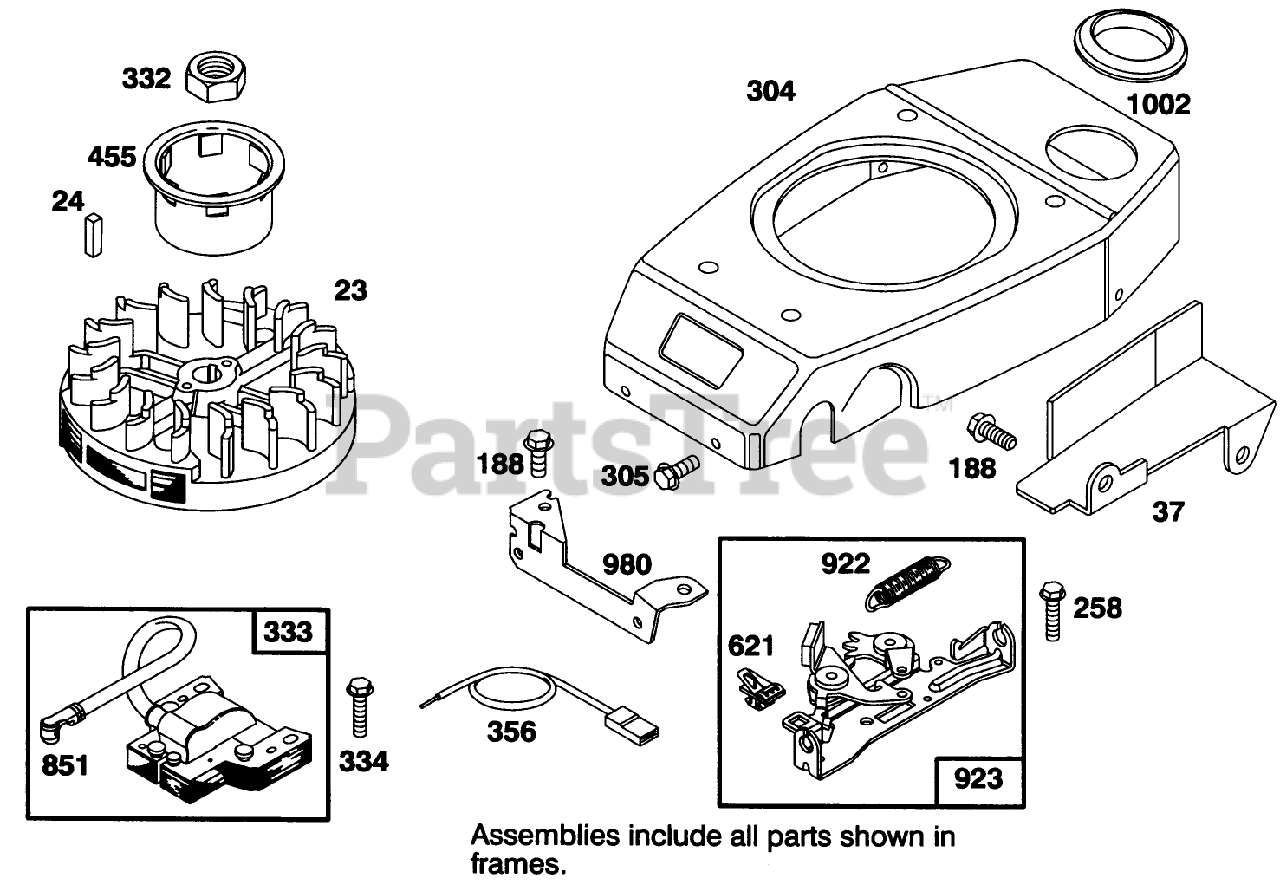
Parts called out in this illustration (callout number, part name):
24	KEY - FLYWHEEL
37	GUARD - FLYWHEEL
304	HOUSING - BLOWER
305	SCREW - HEX HEAD
332	NUT - HEXAGON
334	SCREW - SEM
356	WIRE - GROUND
621	STOP SWITCH
980	BRACKET-BLOWER HSG
